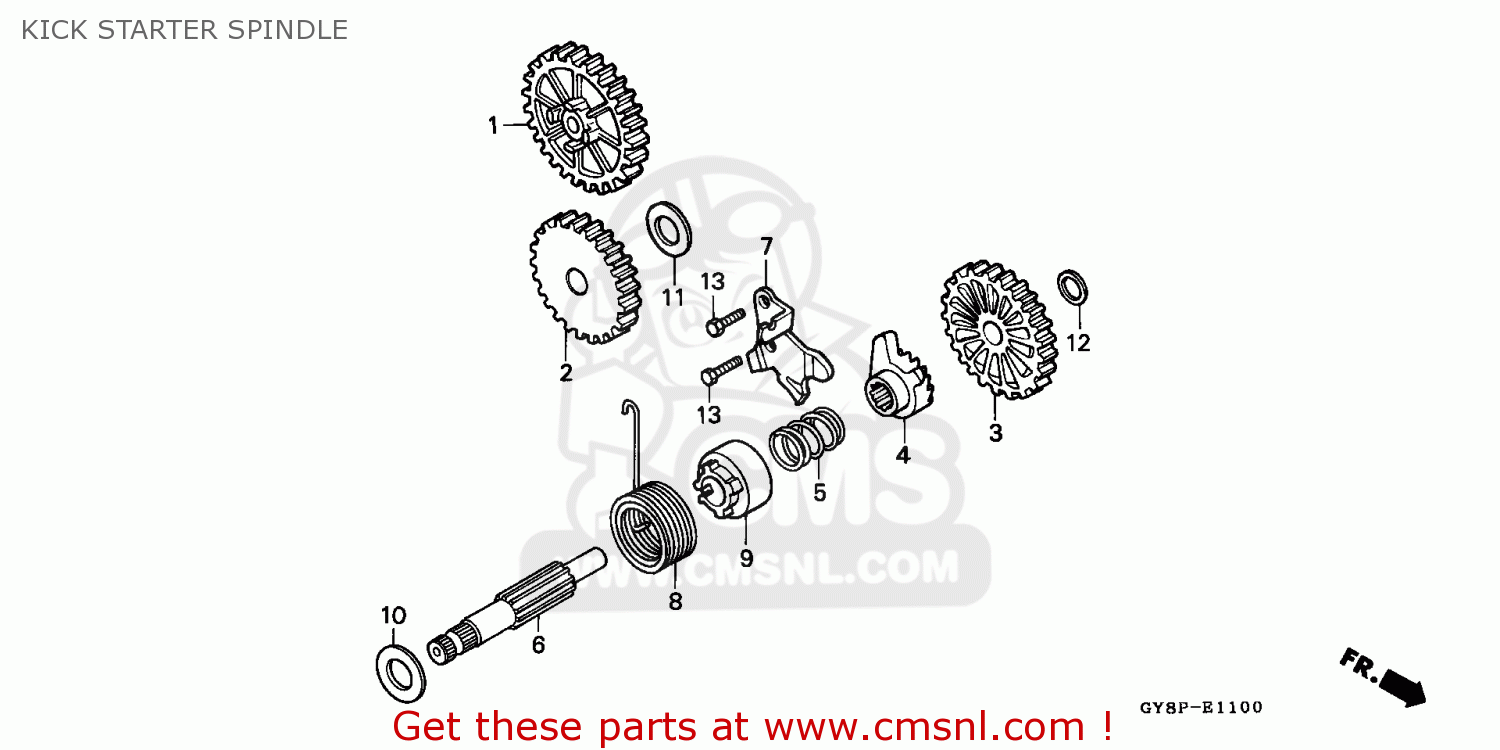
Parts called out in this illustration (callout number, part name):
1	GEAR,OIL PUMP
2	GEAR,IDLE STARTER
3	PINION KICK START
4	RACHET,START.DRIV
5	SPRING,RATCHET
6	SPINDLE,KICK STAR
7	PLATE,RATCHET
8	SPG,KICK STARTER
9	COLLAR,KICK SPG
10	WASHER.16.1M/M
11	WASHER,15MM
12	WASHER,THRUST
13	BOLT,HEX.,6X16
